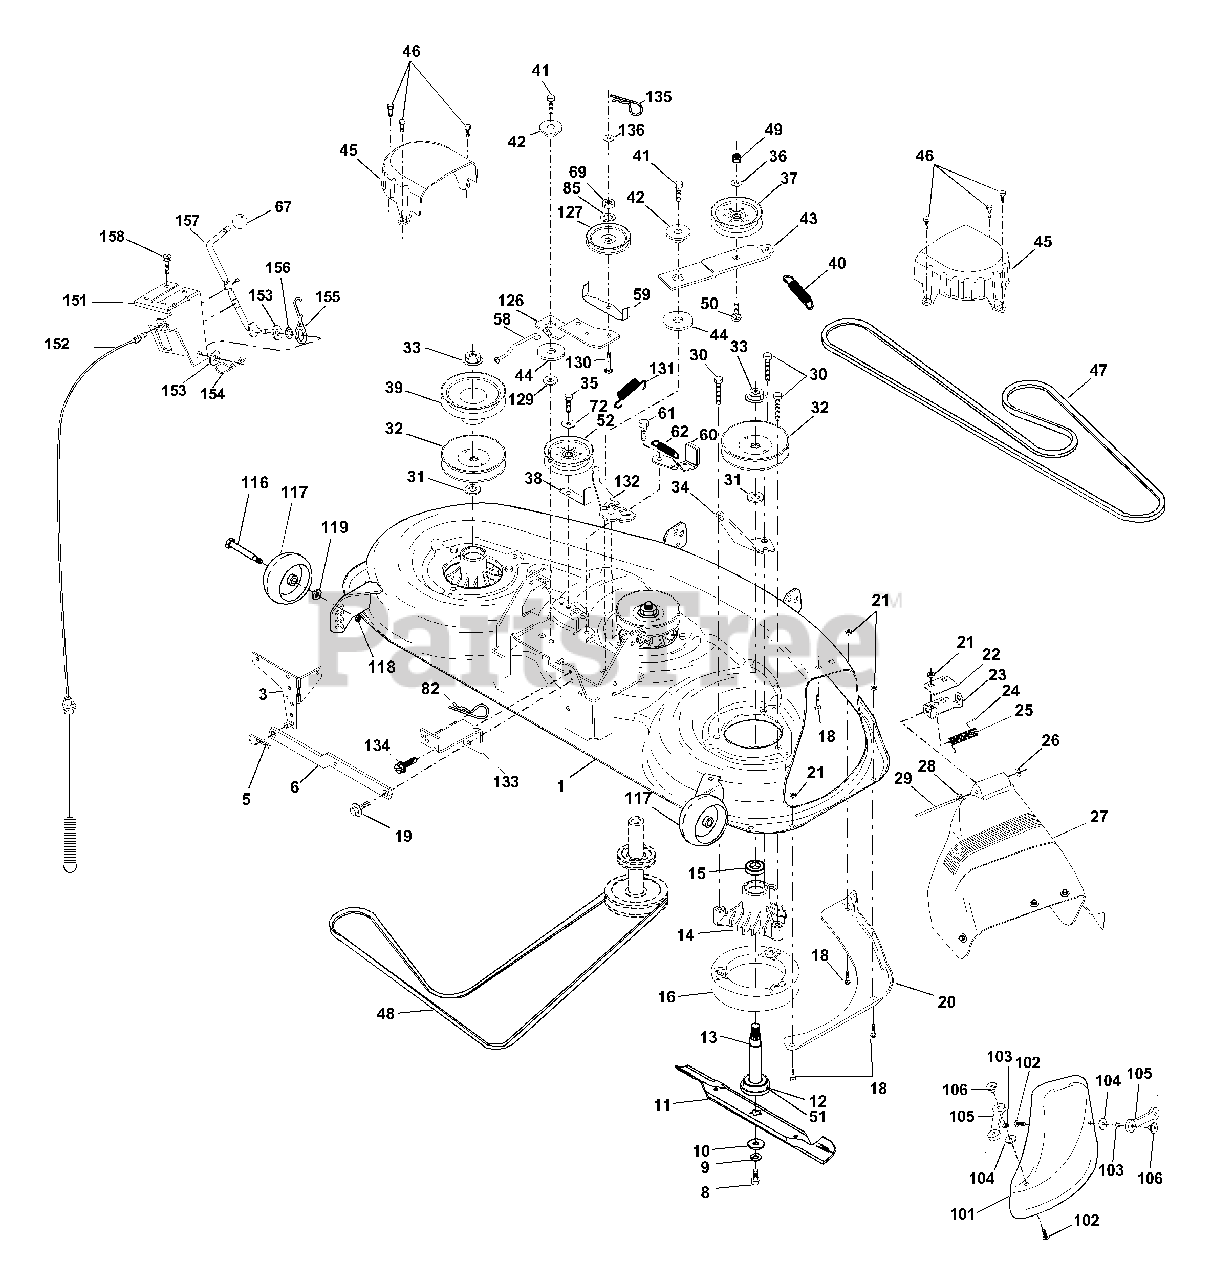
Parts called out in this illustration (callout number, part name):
1	Deck Asm., Mower 46"
3	Bracket Asm., Sway Bar
5	Retainer Spring
6	Arm, Suspension, Rear (Sway Bar)
8	Bolt, Patched 3/8-24 x 1-1/4 Gr. 8
9	Washer, Lock Hvy., Unplated 3/8
10	Washer, Hard Blade, Mower Vented
11	Blade, 46" Mower Deck
12	Bearing, Ball, Mandrel #6204
13	Shaft Asm. w/Lower Bearing
14	Housing, Mandrel
15	Bearing, Ball, Mandrel
16	Stripper, Mower Round
18	Bolt, Carriage 5/16-18 x 5/8
19	Bolt, Hex Head, Shoulder 5/16-18
20	Baffle, Vortex Mower 46"
21	Nut, Crownlock 5/16-18 UNC
22	Stiffiner, Bracket
23	Bracket, Deflector
24	Cap, Sleeve
25	Spring, Torsion, Deflector
26	Nut, Push
27	Deflector Clipping
28	Washer 11/32 x 5/8 x 16 Ga.
29	Rod, Hinge
30	Screw Thd Rolling Washer Head
31	Washer, Spacer Mower Vented
32	Pulley, Mandrel
33	Nut, Flg. Top Lock Cntr. 9/16
34	Anchor, Spring Deck 46"
35	Screw, Thdroll 3/8-16 x 1-3/4 Tytt
36	Washer 13/32 x 13/16 x 16 Ga.
37	Pulley, Idler, Flat
38	Keeper, Belt, Idler
39	Pulley, Idler, Driven
40	Spring, Secondary 44/46/50 Vent
41	Screw, Thdroll 3/8-16 x 1-1/4 Tytt
42	Spacer, Retainer
43	Arm, Idler Secondary
44	Washer,Hardened
45	Cover, Mandrel Deck
46	Screw, Thdroll. 1/4-20 x 5/8
47	V-Belt, Mower, Secondary
48	V-Belt, Mower, Primary
49	Nut, Crownlock 3/8-16 UNC
50	Bolt, Carriage 3/8-16 x 1-1/2 Gr. 5
51	Washer Felt
52	Pulley Idler
58	Rod Brake 46"
59	Guide Belt 46"
60	Arm Asm Brake
61	Bolt Shld 5/16-18 Ty TT
62	Spring Return
67	Knob Rd 3/8-16 Plstc Thds Blk
69	Nut Hex Jam 3/8-16 UNC
72	Washer 13/32 x 13/16 x 16 Ga.
82	Retainer Spring 1"
85	Washer Lock Hvy Hlcl Spr. 3/8
101	Cover Mulch
102	Screw Truss Hd Phil 10-24 x 5/8
103	Washer Lock #10
104	Washer #10
105	Latch Asm. Mulch/Bagger
106	Nut Weld
116	Bolt, Shoulder
117	Gauge Wheel
118	Nut, Centerlock 3/8-16 UNC
119	Washer 3/8 x 7/8 x 14 Ga.
126	Arm, Idler, Primary Deck 46"
127	Pulley, Idler, V-Groove Dim. 4.25
129	Washer 13/32 x 2-3/8 x 8 Ga.
130	Bolt Carriage Idler
131	Spring Return Idler
132	Arm Spring Brake Mower
133	Bracket Anchor Cable 46"
134	Screw thdrol 5/16-18 x 3/4
135	Retainer Spring Yellow
136	Washer 9/32 x 3/4 x 16 Ga.
151	Bracket Clutch Cable
152	Clutch Cable
153	Washer Flat 3/8" Type B
154	Spring Retainer
155	Spring Retention Lvr Clutch Cable
156	Spacer Clutch Cable
157	Rod Clutch Cable 3/8"
158	Screw Hex Thd Cut 1/4-20 x 5/8
